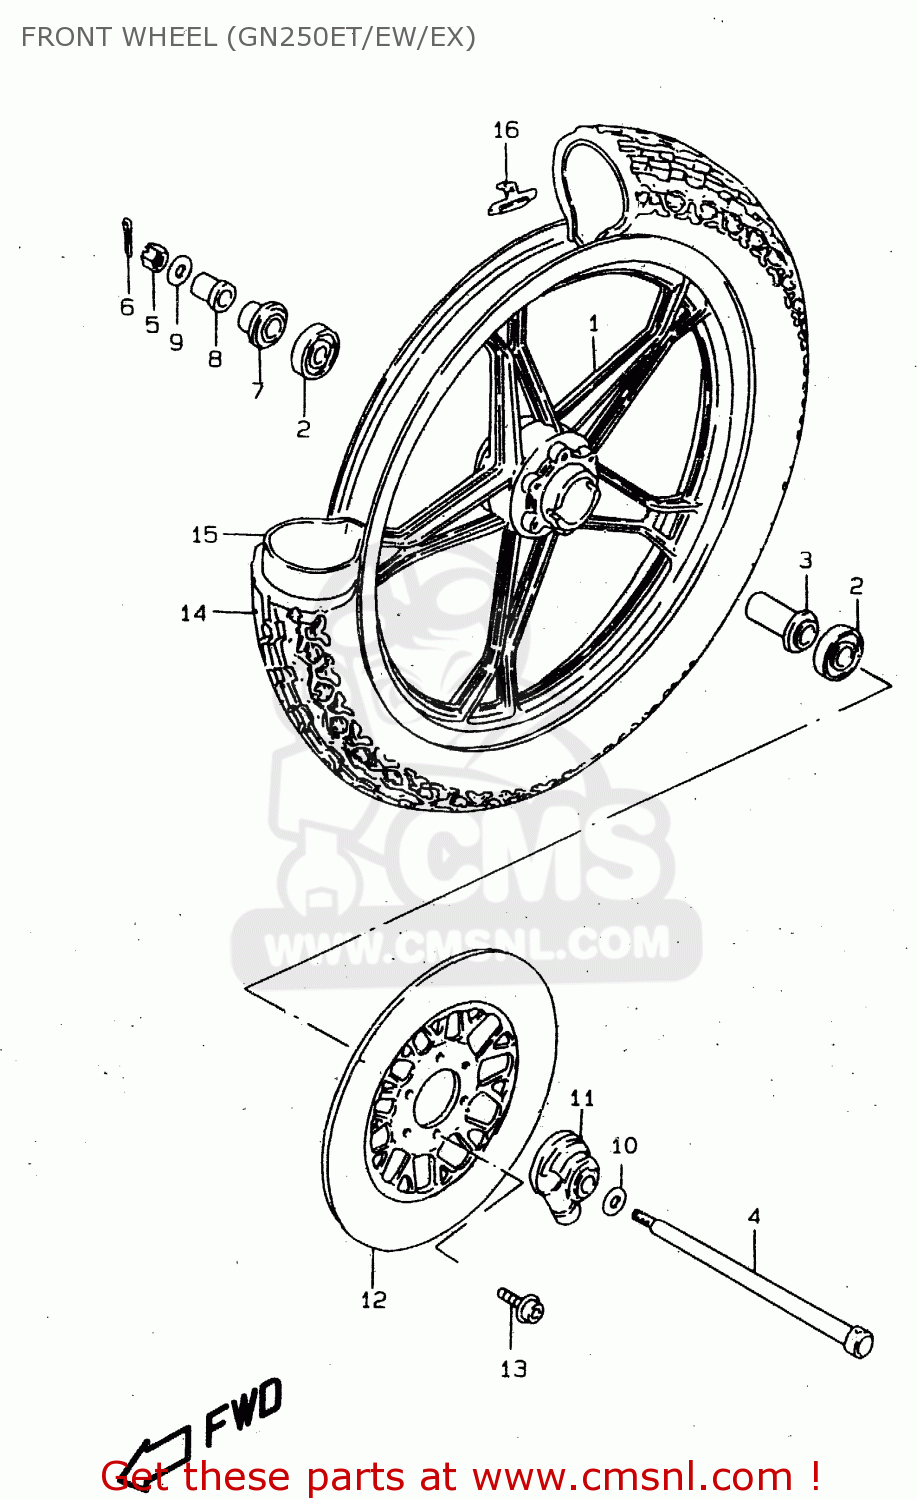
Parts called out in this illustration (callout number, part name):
1	WHEEL,FRONT (1.60X18)
2	BEARING
3	SPACER,FR HUB BEARING
4	AXLE,FR
5	NUT
6	COTTER PIN
7	SPACER,FR AXLE,R
8	SPACER
9	WASHER
10	WASHER(15.5X26X2.3)
11	BOX ASSY,SPEEDOMETER GEAR
12	DISC,FR BRAKE
13	BOLT(8X30)
14	TIRE,FR(3.00-18 47S GS-11)
15	TUBE,INNER
16	BALANCER,WHEEL (10G)
